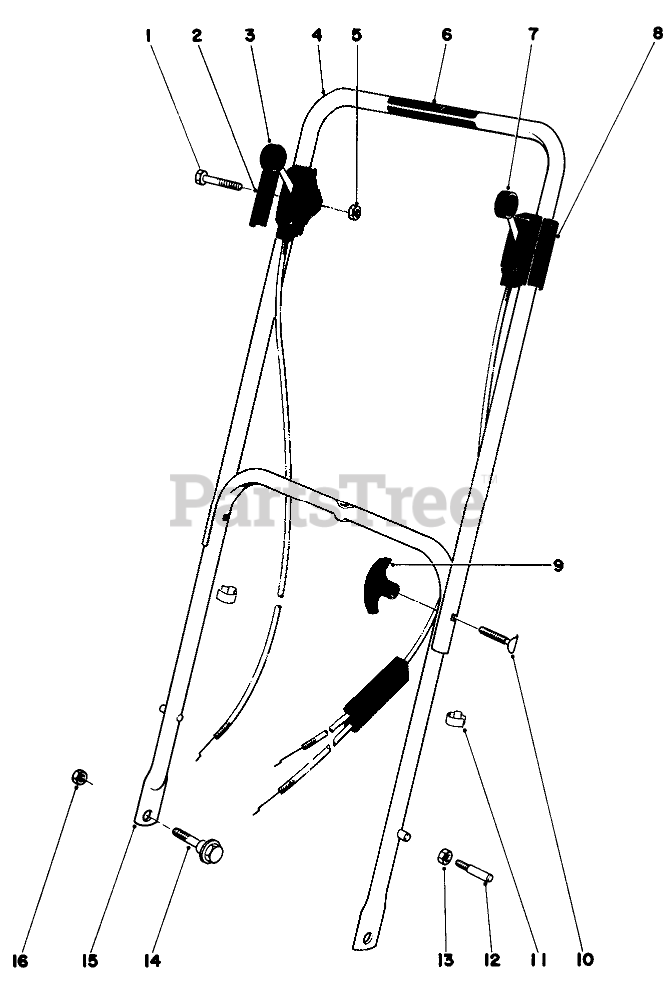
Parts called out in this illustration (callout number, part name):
1	SCREW-HH
2	Decal-Throttle
3	Throttle Control
4	Upper Handle
5	NUT-LOCK
6	Decal
7	Traction Control
8	Decal-Traction Control
10	HANDLE SCREW
11	BOWDEN CLIP
12	HANDLE PIN
13	Nut
14	SCREW-SHOULDER
15	Lower Handle
16	Nut
